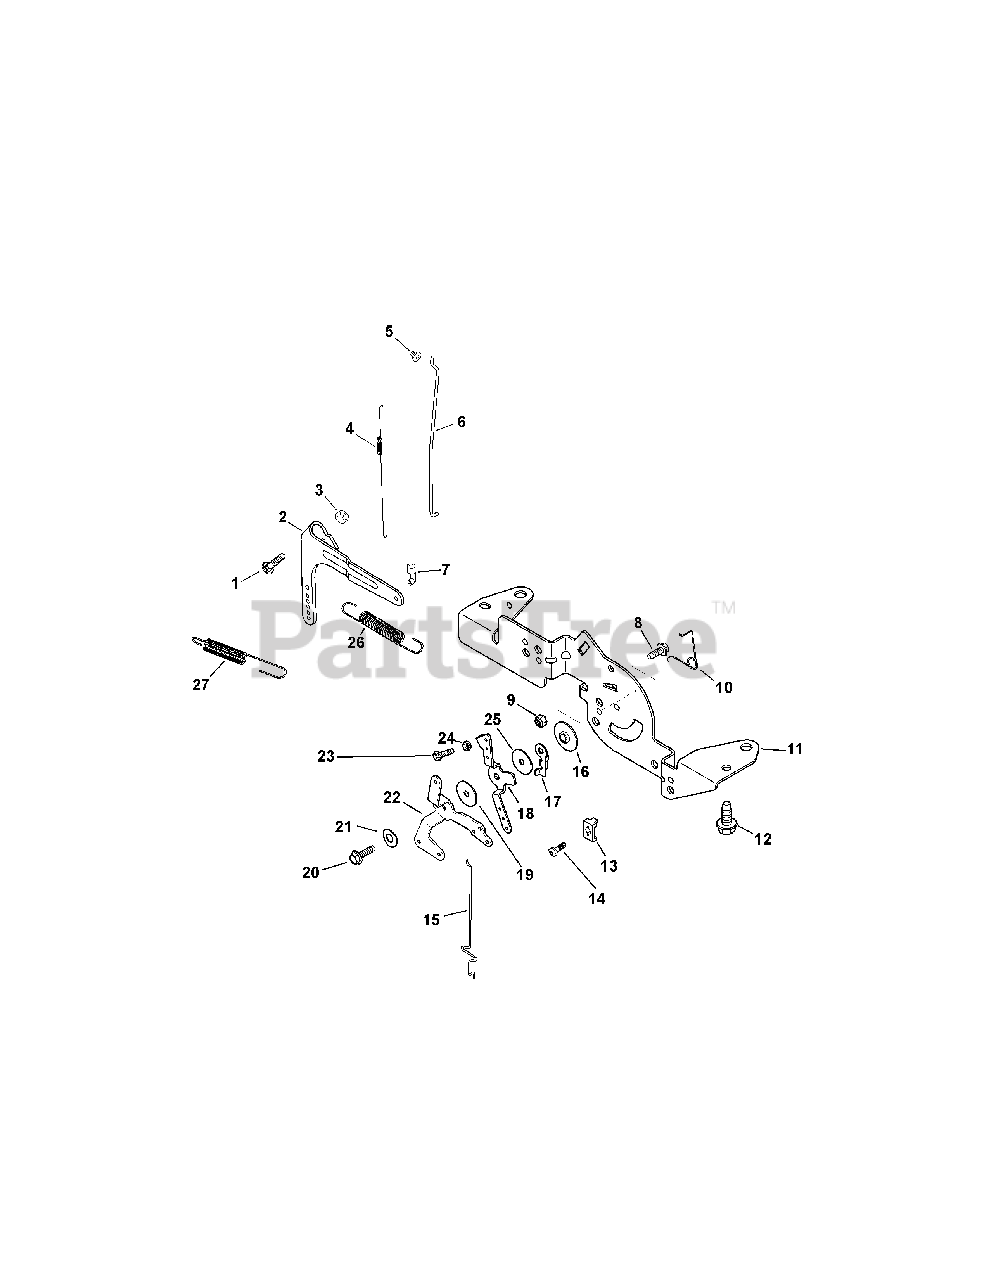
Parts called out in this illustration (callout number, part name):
1	Bolt, M6 x 1.0 x 25
2	Governor Lever
3	Flange Nut, M6 x 1.0
4	Linkage Spring
5	Linkage Retaining Bushing
6	Throttle Linkage
7	Throttle Linkage Bushing
8	Flange Screw, M5 x .8 x 16
9	Lock Nut, M5 x .8
10	Choke Return Spring
11	Control Bracket
12	Flange Screw, M6 x 1.0 x 16
13	Cable Clamp
14	Screw, M5 x .8 x 16
15	Choke Linkage
16	Control Assembly Spacer
17	Throttle Actuator Lever
18	Throttle Control Lever
19	Flat Washer, 5.5mm
20	Flange Screw, M5 x .8 x 20
21	Spring Washer, 1/4
23	Screw, M4 x .7 x 25
25	Flat Washer, 5mm
26	Governor Spring
27	Governor Spring
